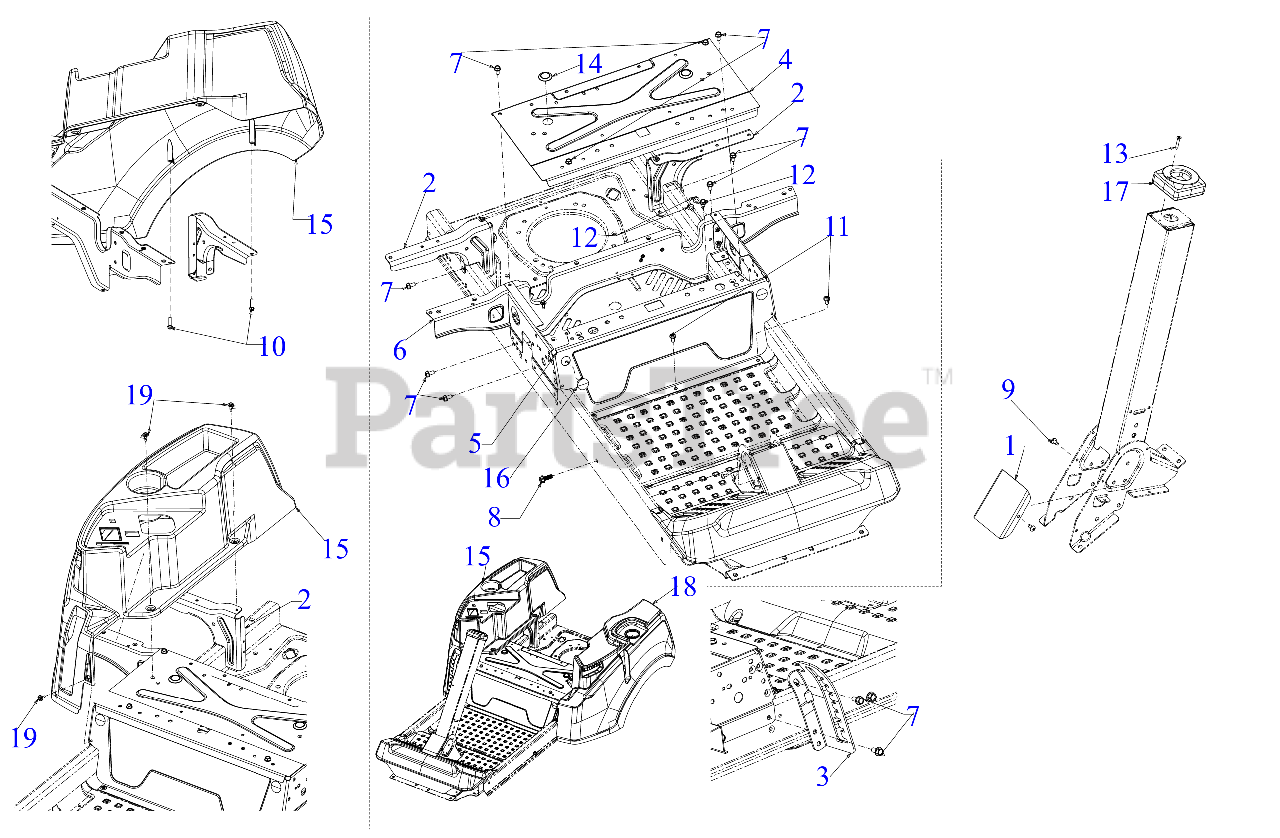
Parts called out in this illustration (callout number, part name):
3	HEIGHT INDEX BRACKET
7	SCREW 5/16-18 x .750
8	SCREW 3/8-16 x 1
9	SCREW 1/4-20 x .5
10	SCREW 5/16-14 x 1
11	SCREW 5/16-18 x .750
12	SCREW 5/16-18 x .500
13	SCREW #10-16 x 1.25
15	CONSOLE (RH)
16	PLASTIC PLUG
17	STEERING COLUMN COVER
18	CONSOLE (LH)
19	SHOULDER SCREW M6-1 .368 X.115
